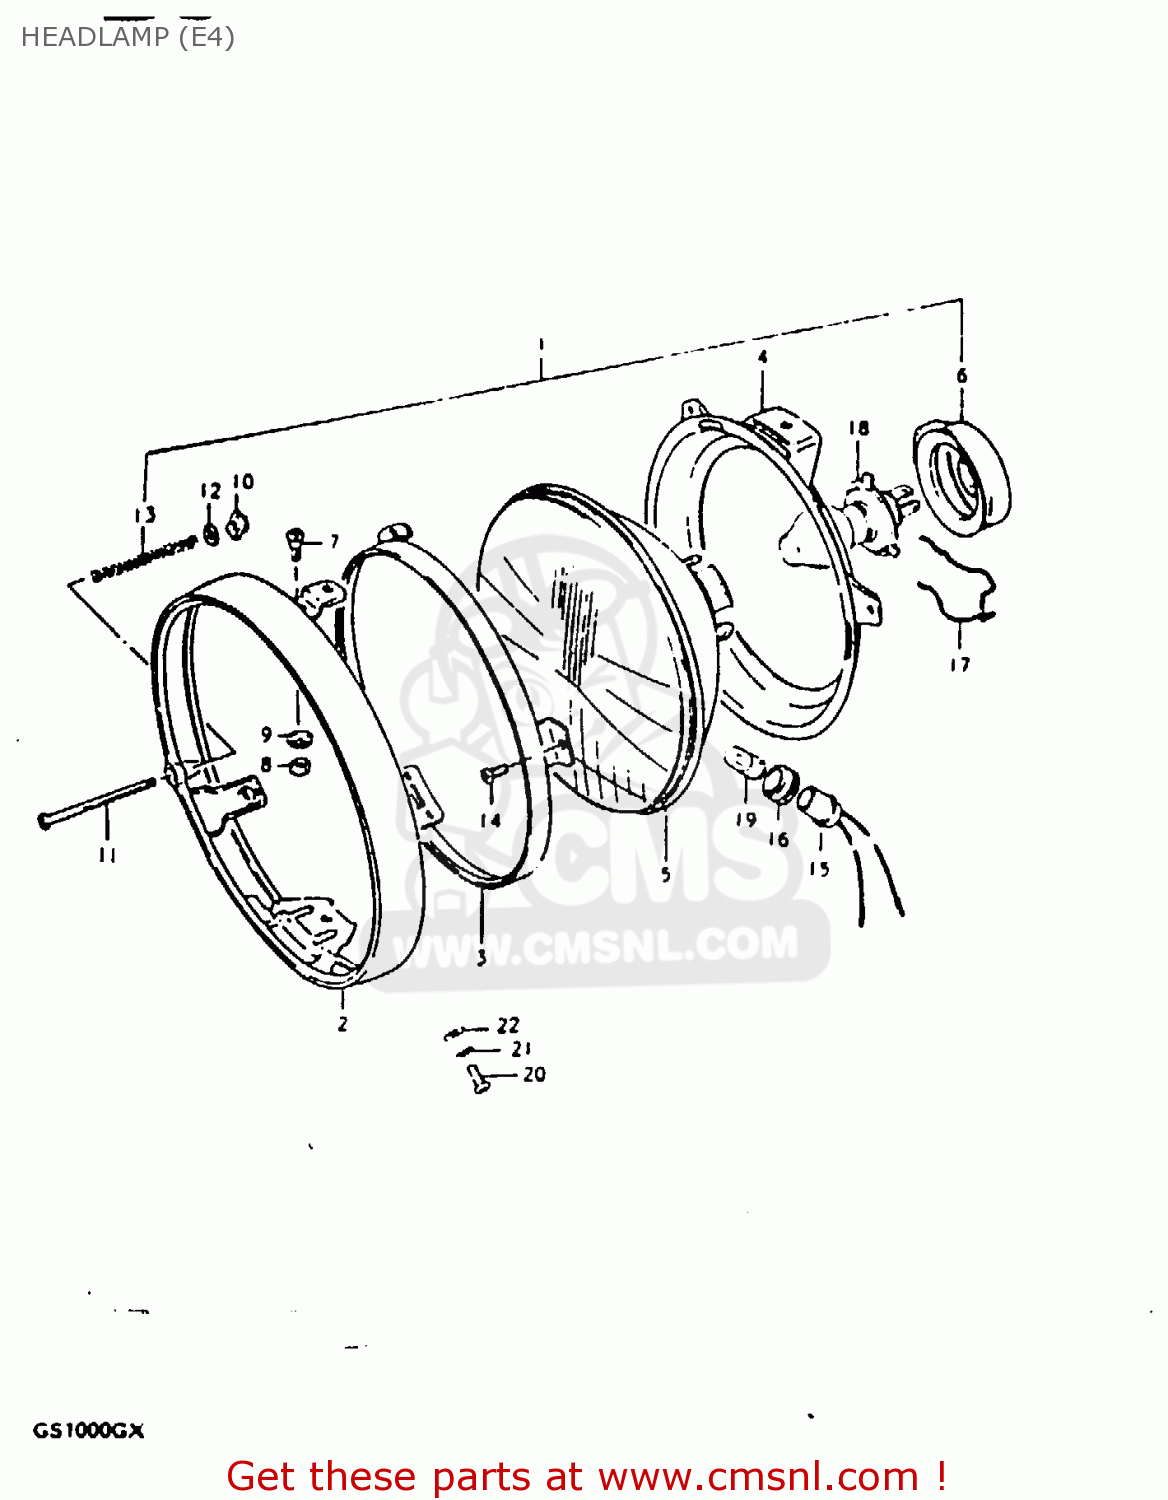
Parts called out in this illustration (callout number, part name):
1	HEADLAMP ASSY
2	RIM
3	RETAINER
4	RING,HEADLAMP UNIT
5	UNIT,HEAD LAMP
6	COVER,HEADLAMP SOCKET
7	SCREW
8	NUT,ADJUSTING
9	SPACER
10	NUT
11	SCREW,HEADLAMP ADJUST
12	WASHER
13	SPRING,HEADLAMP ADJUST
14	SCREW
15	SOCKET
16	JOINT,RUBBER
17	CLAMP,HEADLAMP SOCKET
18	BULB (12V, 60/55W, H4)
19	BULB(12V4W)
20	SCREW
21	WASHER,LOCK
22	WASHER
